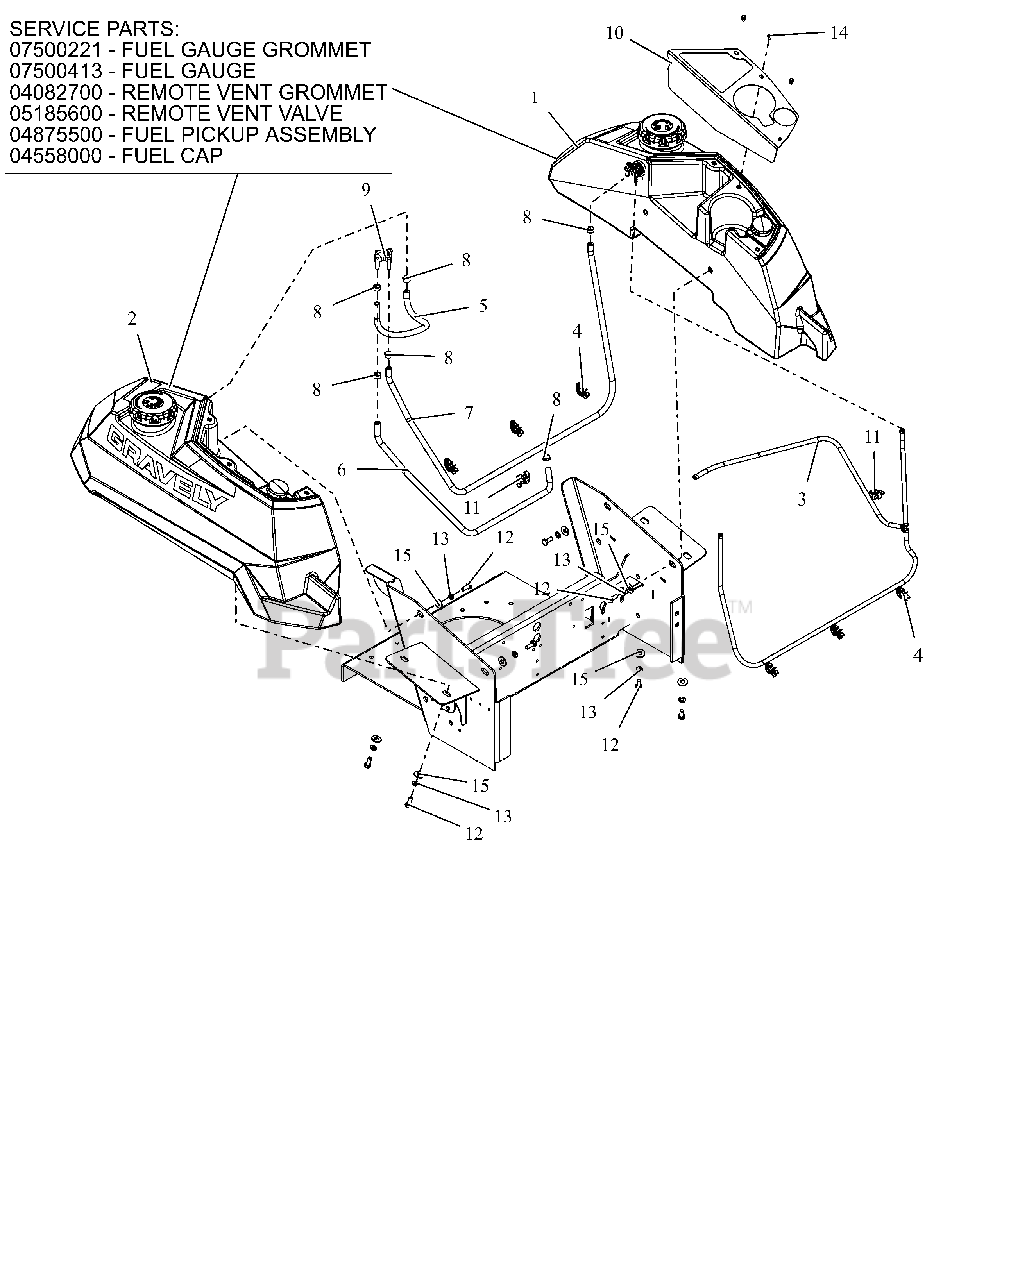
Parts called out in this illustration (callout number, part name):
1	ASM, LH - PT100 FUEL TANK
2	ASM, RH - PT100 FUEL TANK
2	GROMMET, FUEL GAUGE
2	GAUGE, REMOTE SEALED FUEL
2	GROMMET, REMOTE VENT NITRILE
2	VALVE, COMBINATION VENT 3/16
2	ASSM,LRG TANK FUEL PICKUP LINE
2	CAP, FUEL VENTIN AUTOLOCK
3	ASM, VAPOR LINE
4	WIRE CLIP
5	HOSE, .25 LOW-PERM BULK GAS
6	HOSE, .25 LOW-PERM BULK GAS
7	HOSE, .25 LOW-PERM BULK GAS
8	CLAMP, FUEL LINE
9	VALVE, FUEL
10	PT100 CUPHOLDER PANEL - RED
11	CLIP, T, .38-.50
12	@BLT-HEX .31-18X.75 GR5 YWZC
13	@WSHR-LK .31X.078 REG YWZC
14	SCR-MCH 10-24X.38 HWHSTAINLESS
15	@WSHR-FL-STL.38X.875X.083 YWZC
